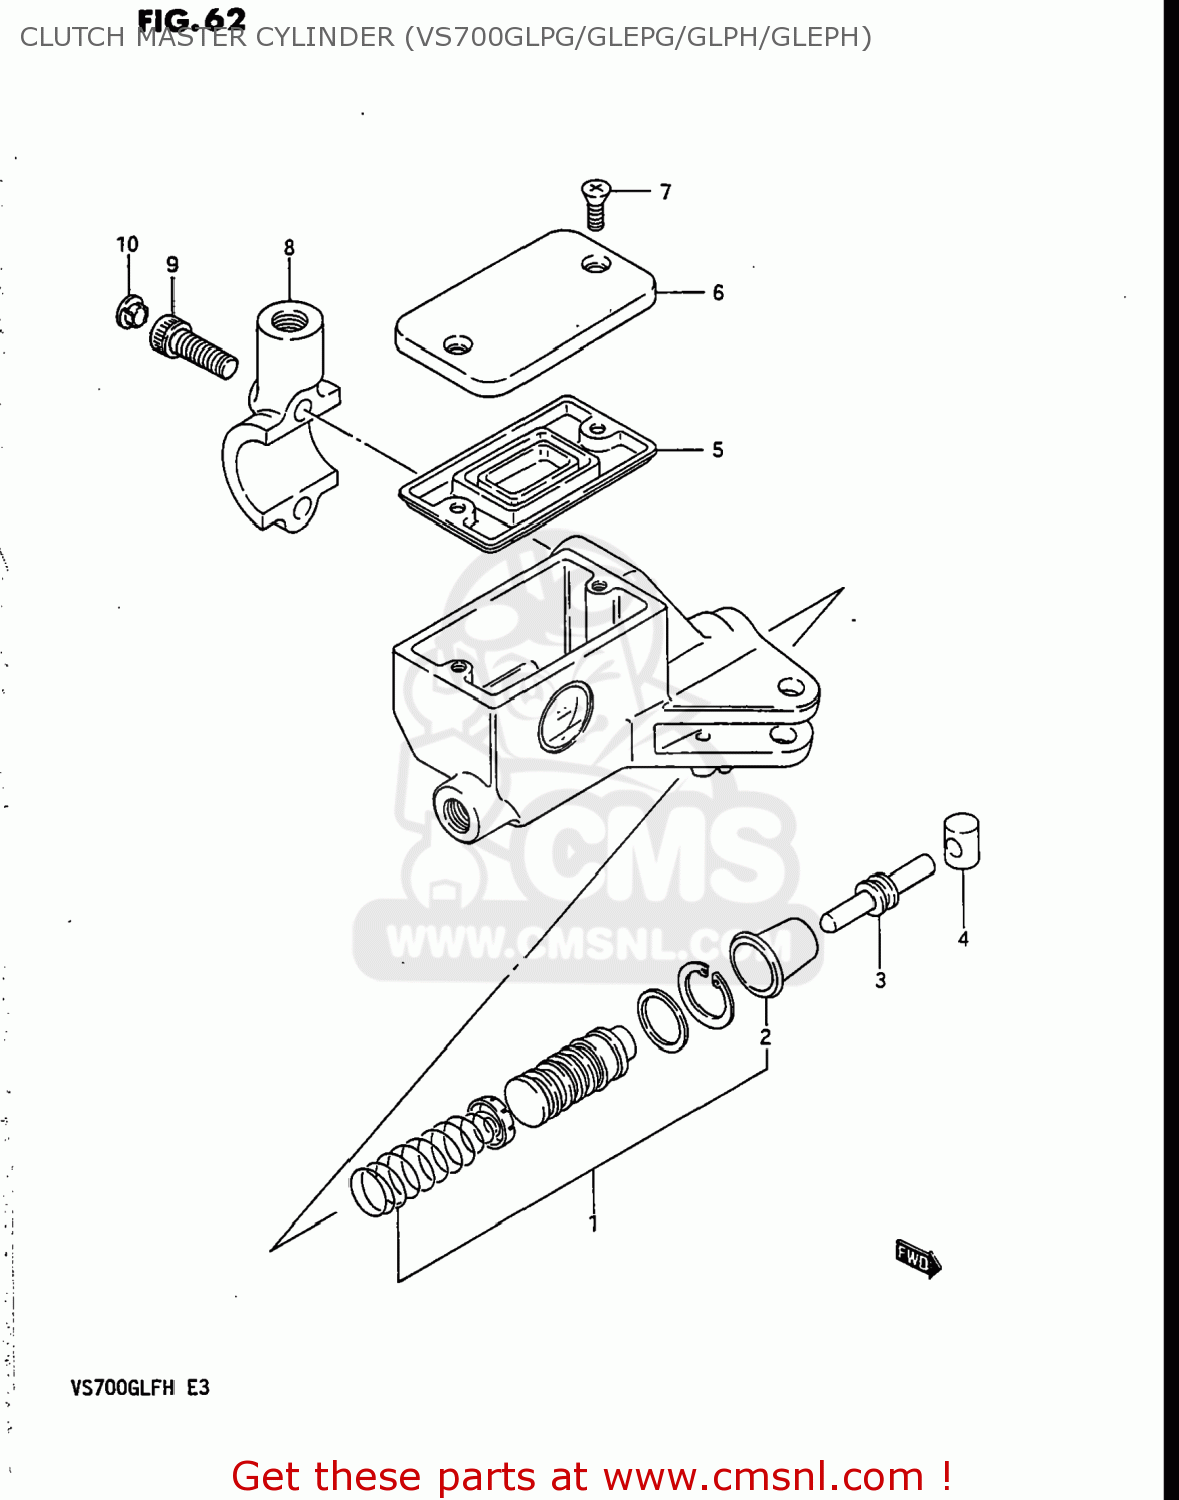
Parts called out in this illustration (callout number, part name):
1	PISTON & CUP SET
2	BOOT
3	PUSH ROD
4	BUSH
5	6
6	CAP
7	SCREW,RESERVOIR CAP
8	HOLDER
9	BOLT ,6X20
10	CAP(OD:10)
